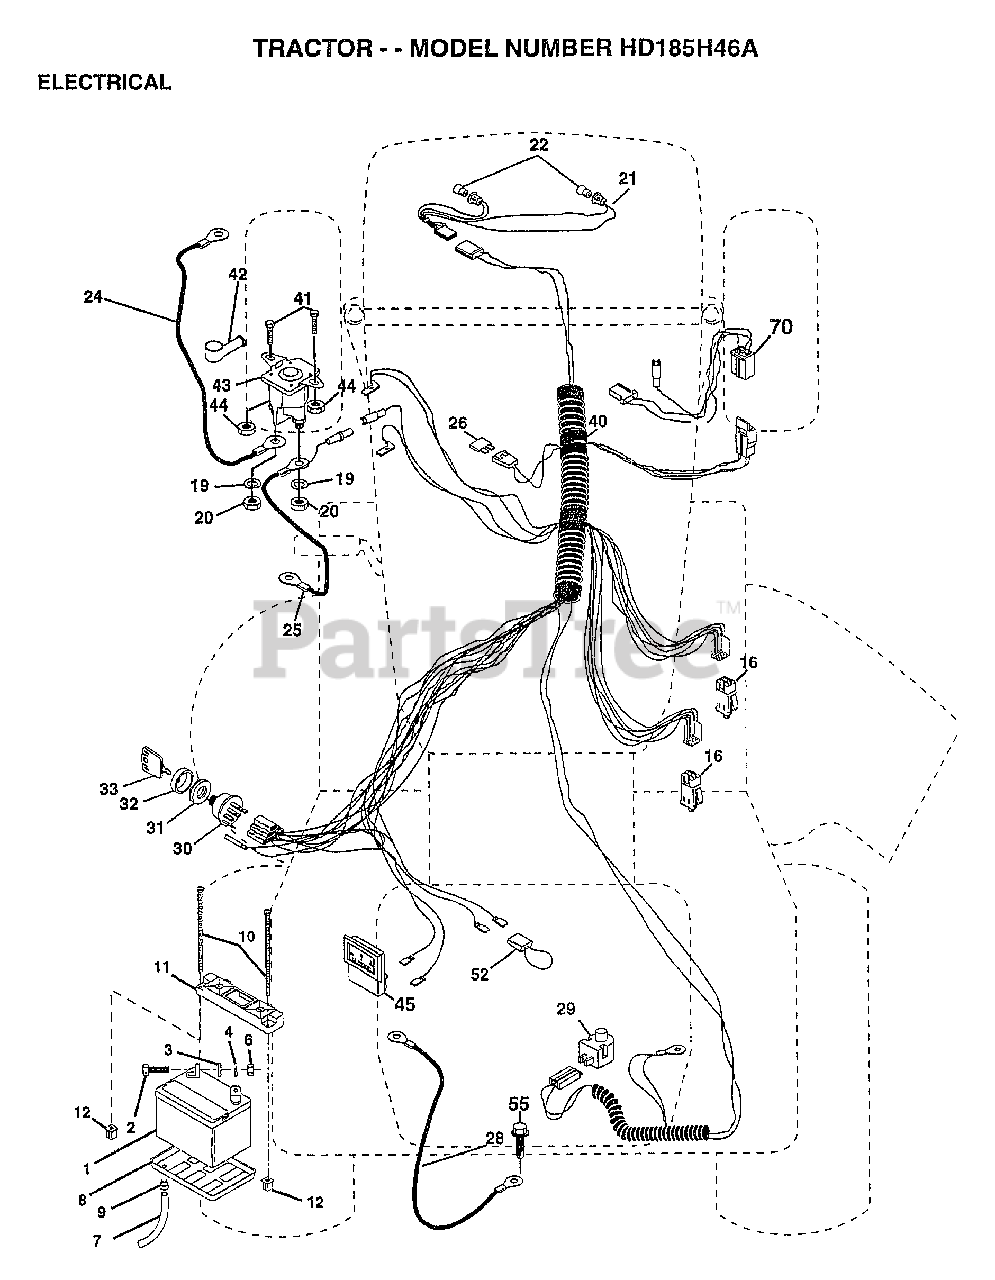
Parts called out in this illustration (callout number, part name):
2	BOLT LT
3	WASHER
4	LOCKWASHER
7	"DRAIN TU T, BATT"
8	"TRAY T, BATTERY"
9	HOSE CLAMP T
11	HOLDDOWN BATTERY
16	SWITCH INTERLOCK
20	NUT
21	"HARNESS,LIGHT SOC"
22	HEADLAMP BULB
24	"CABLE T, BATTERY"
25	CABLE.6GA.22W/16W
26	FUSE HYT
28	CABLE.GRND.6GA.21
29	SWITCH SEAT
30	SWITCH IGN 4POS
32	COVER KEY SWITCH
33	KEY
40	HARNESS-IGNITION
41	BOLT HXHD FIN
44	NUT HXKEP 1/4X20
52	PROTECTION LOOP
55	SCREW LT
70	HARNESS ENG DUAL
